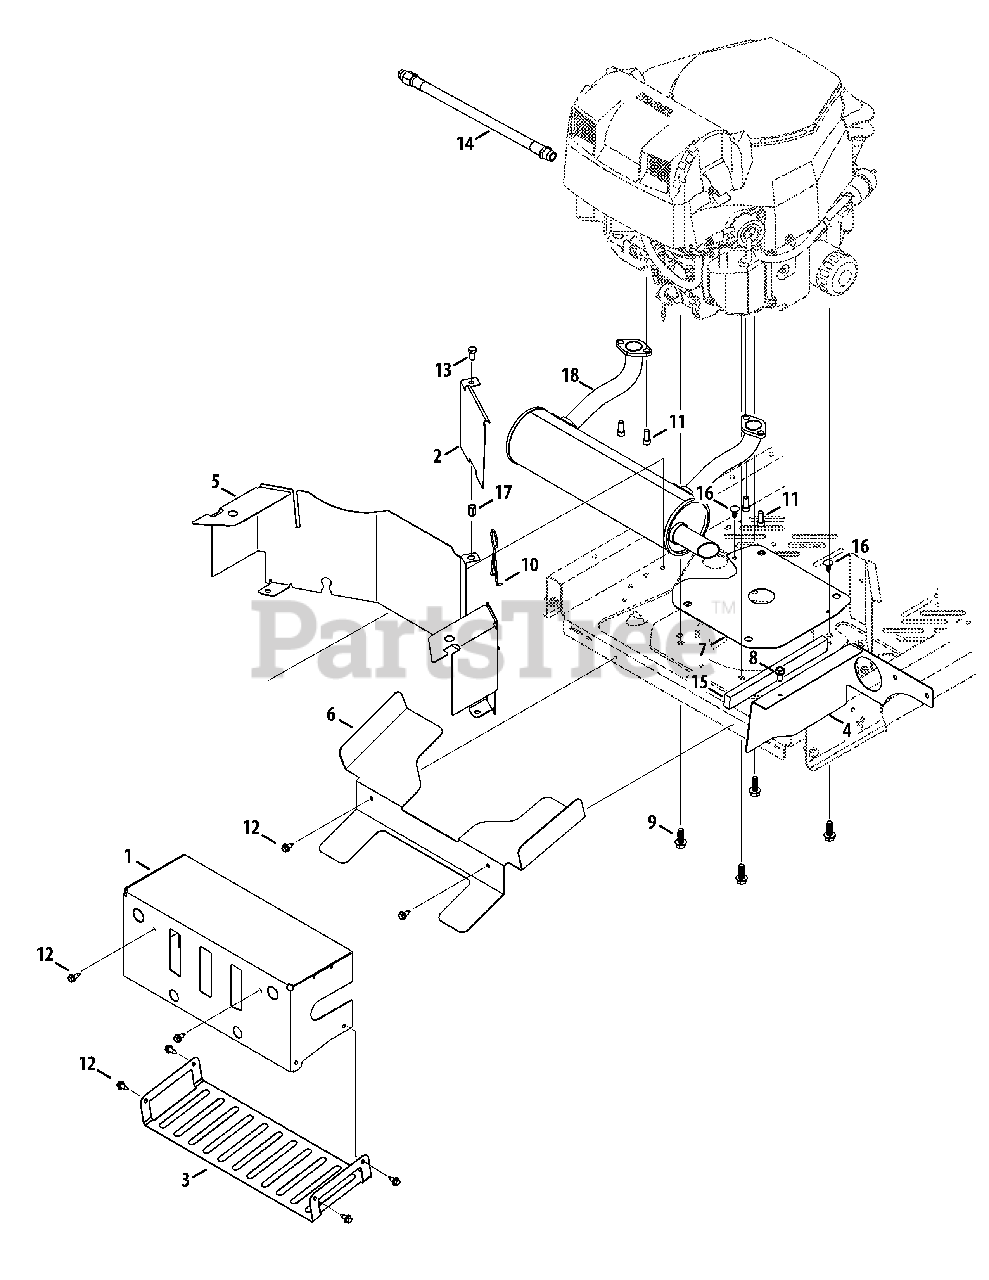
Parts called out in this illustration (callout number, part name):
1	Muffler Shield Bracket
2	Engine Shield Bracket
3	Lower Muffler Shield Bracket
4	Pod Shield Bracket, RH
5	Engine Shield Bracket
6	Muffler Mounting Bracket
7	Engine Shield Plate
8	SCREW 5/16-18 x .750
9	Screw, 3/8-16 x 1.00
10	Tank Support Rod
11	Socket Head Screw, 5/16-18 x .750
12	Hex Washer Screw, 1/4-20 x .625
13	Hex Cap Screw, 5/16-18 x .625
14	Oil Drain Hose
15	Foam Tape, 1.00 x .500 x 9.375
16	Ratchet Clip, .250
17	Nut, 5/16-18
18	Twin Muffler
